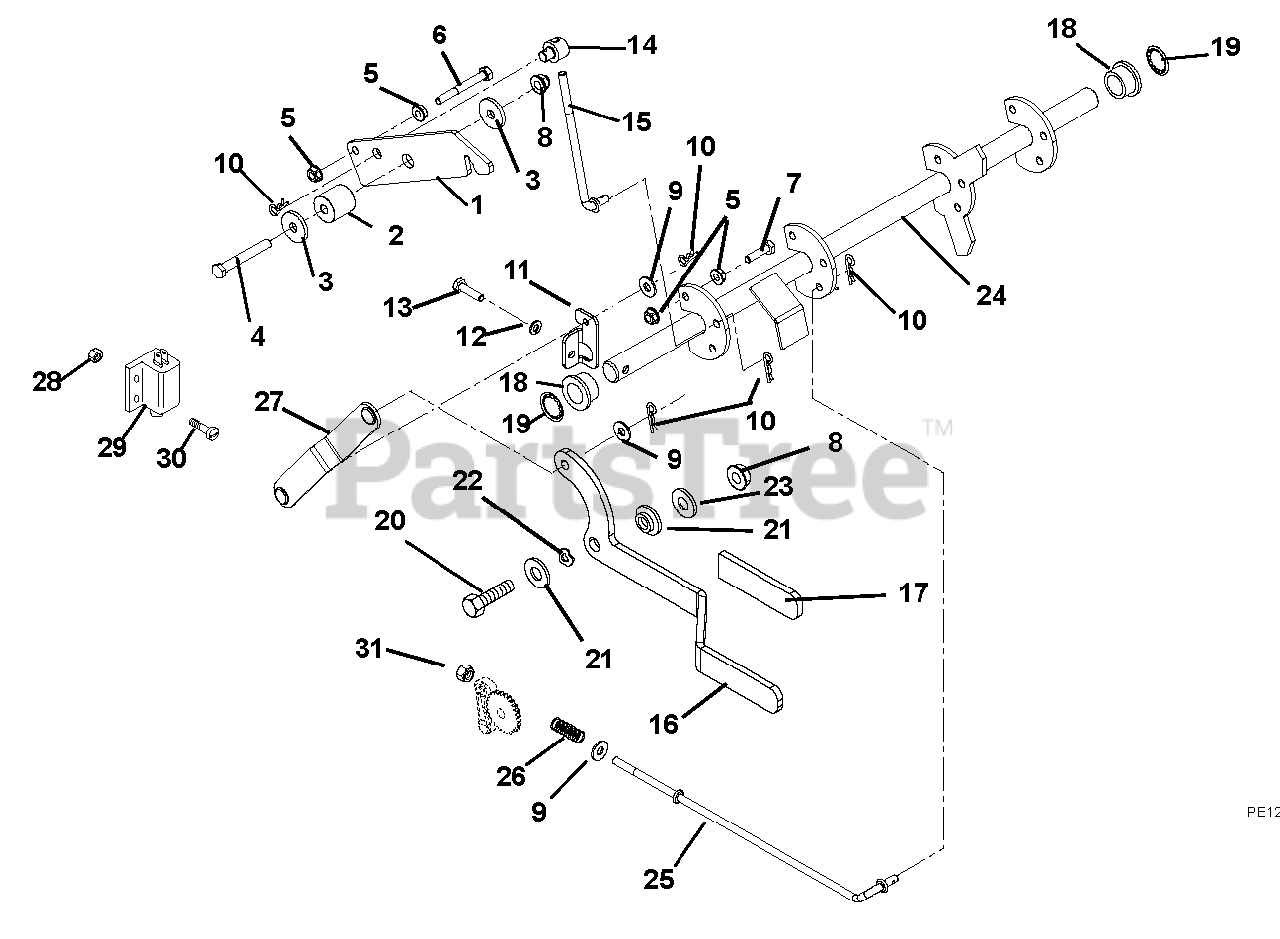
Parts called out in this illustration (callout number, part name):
1	Latch, Neutral
3	Washer, Flat Steel .344 x 1.125 x .135
4	Bolt, Hex .31-18 x 2.25 Grade 5
5	Nut, Locking Flange .250-20
6	Bolt, Hex .25-20 x 2.25 Grade 5
7	Bolt, Hex .25-20 x 1.00 Grade 5
8	Nut, Flange Nyloc 5/16-18
9	Washer, Flat Steel .312 x .734 x .065
10	Pin, Hair Internal .08 x .18 x 1.18
11	Crank, Parking Brake
12	Washer, Locking .25 x .062 Regular
13	Bolt, Hex .25-20 x 1.00 Grade 5
14	Trunnion, Brake
15	Brake, Link
16	Handle, Parking Brake
17	Grip, Parking Brake
18	Bushing, Flanged .750 x 1.000 x .625 x 1.250
19	Push Nut, .745 Shaft
20	Bolt, Hex .31-18 x 1.75 Grade 5
21	Bushing, Flange .325 x .501 x .250 x 1.12
22	Washer, Wave .50 x .75 x .015
23	Washer, Flat Steel, .328 x .87 x .179
24	Weldment, Brake Shaft
25	Rod, Brake
26	Spring, Compression .045 x .50 x 1.187
27	Link, Parking Brake
28	Nut, Locking Nylon 10-24 with Insert
29	Switch, Double Pole
30	Screw, Machine 10-24 x .75
31	Nut, Locking-Nylon .250-20
